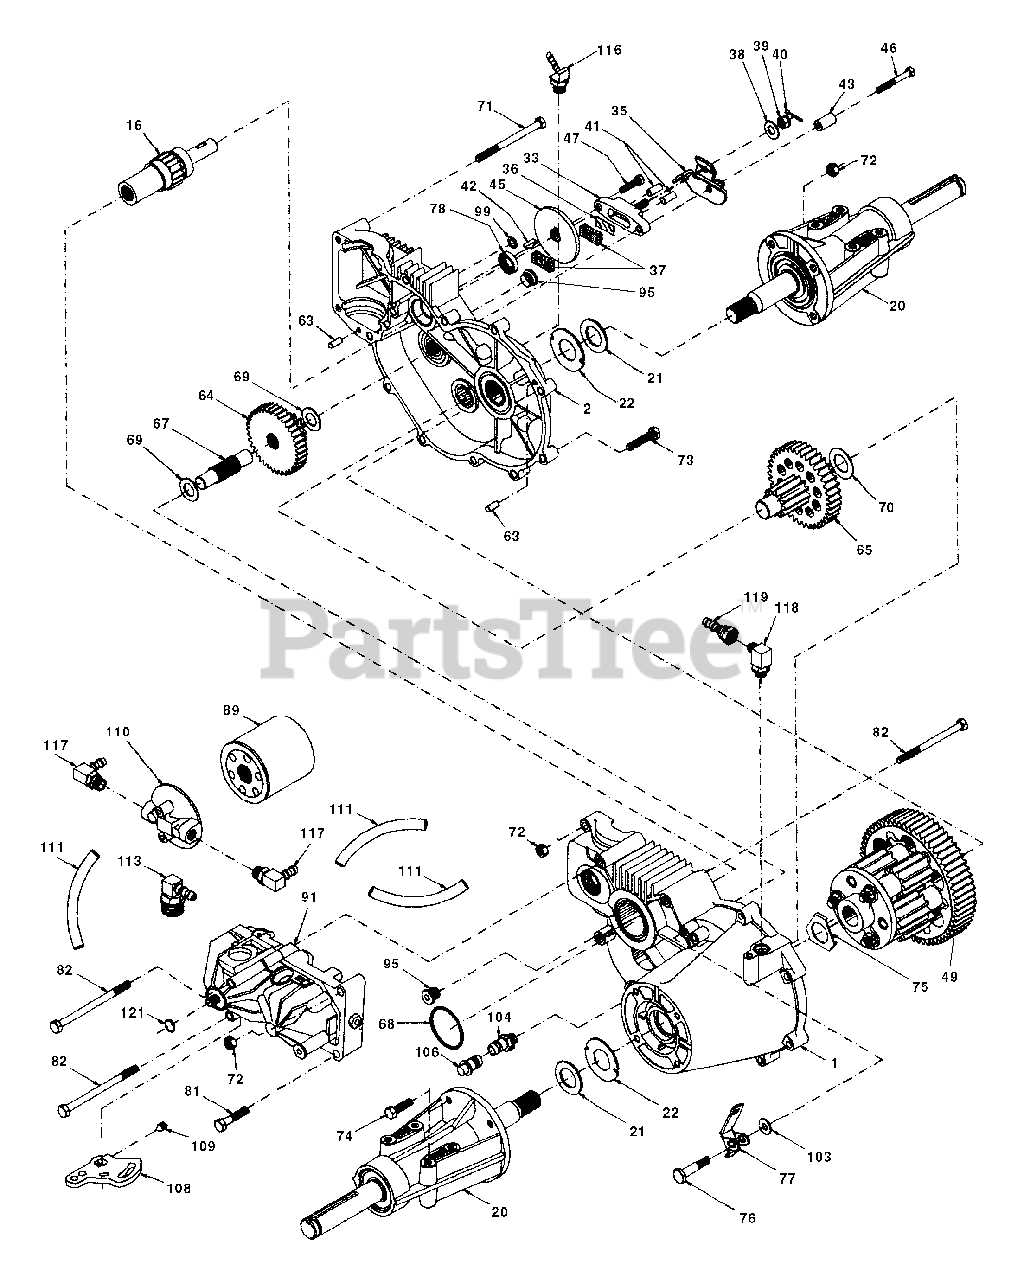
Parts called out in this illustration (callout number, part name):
1	Assembly, Lh Housing
2	Assembly, Rh Housing
16	Brake Shaft Assembly
20	Axle Mounting Horn Ass'y
21	Washer,1.0x1.63x.08
22	Washer,1.0x2.06x.09
33	Brake Yoke Assembly
36	Puck Plate
37	Brake Puck
38	Washer,7/8odx7/16x.060
39	Castle Nut, 5/16-24
40	Cotter Pin
41	Brake Actuating Pin
42	Hi Pro Key
45	Brake Disc
46	Bolt, 1/4-20 X 1-1/2
47	Bolt, 1/4-20 X 1
49	Differential Assembly
64	14t-38t Reduction Gear
65	Final Drive Pinion Ass'y
67	Jack Shaft
69	Washer,5/8 X 1-5/32
70	Washer,7/8 X 1-1/2
71	Bolt, Hex 5/16-18 X 3.5
72	Hex Lock Nut, 5/16-18
73	Bolt, Hex 5/16-18 X 1-1/2
74	Hex Cap Screw, 5/16-18 X 1
75	Washer, Differential
76	Shoulder Bolt
77	Freewheel Actuating Arm
78	Oil Seal, .625 X 1.0 X .25
81	Bolt, Hex 5/16-18 X 1-3/4
82	Bolt, 5/16-18 X 4-1/2
89	Spin On Filter
91	Bdu-10l-118
95	Straight Thread Plug
99	Washer, 11/32 X 9/16
104	Cap-Vent Assembly
106	Fitting-O Ring Assembly
108	Control Arm
110	Filter Head
111	Hose, 5/16 X 12" Long
113	90° 7/8 Sae Fitting
116	45° 9/16 Sae Fitting
117	90° 9/16 Sae Fitting
118	90° Sae #6 Flare Male Fitting
119	90° Sae #6 Flare Female Fitting
121	Wire Retaining Ring
